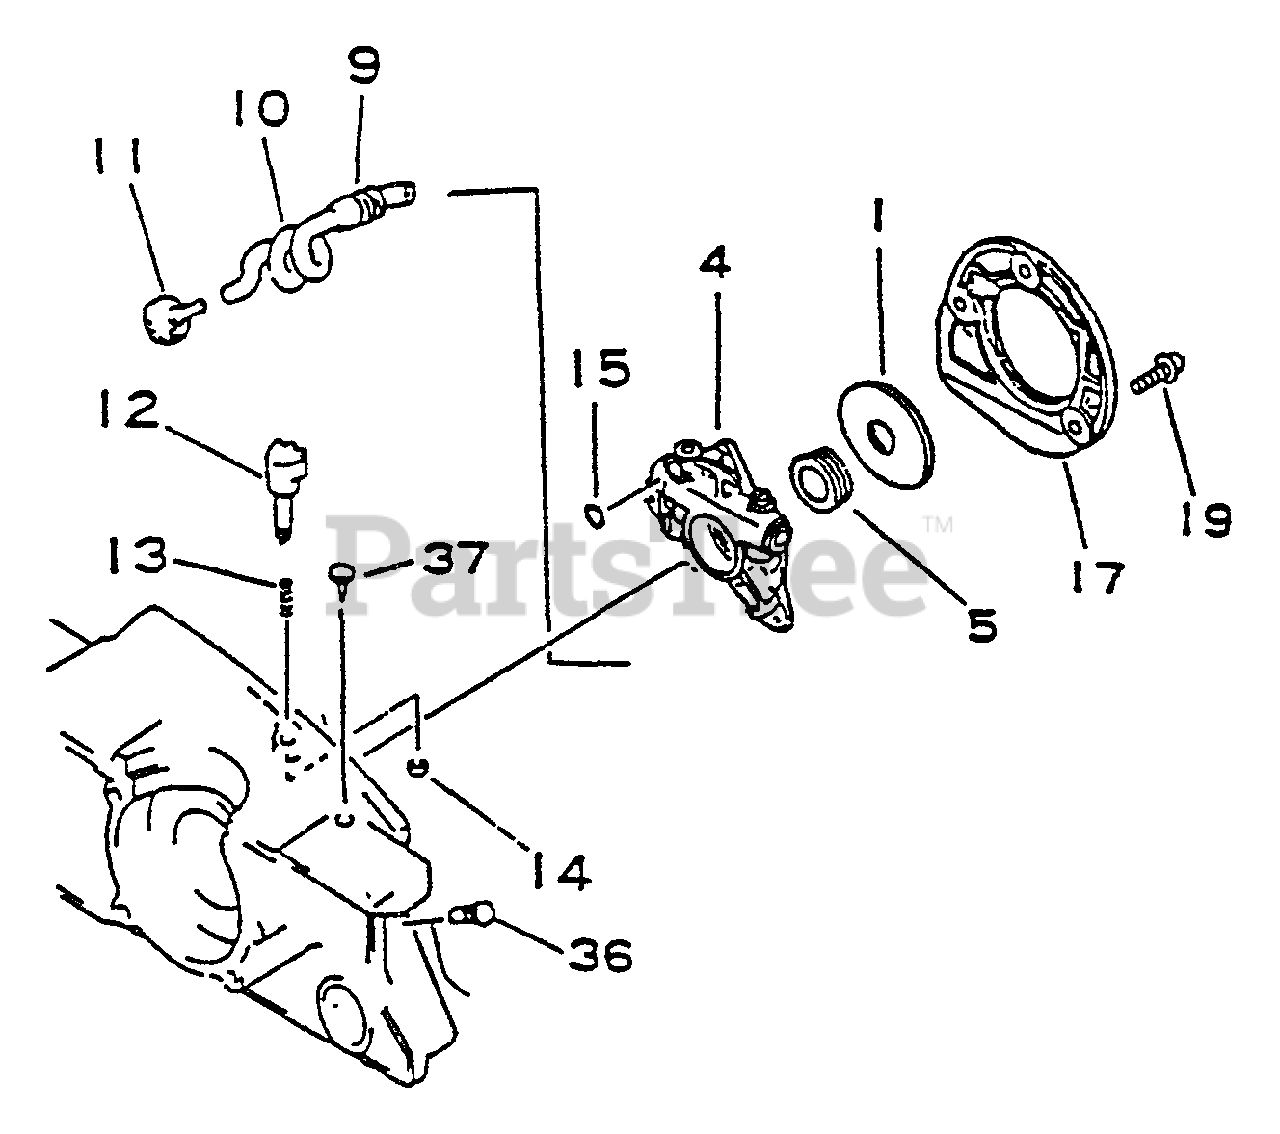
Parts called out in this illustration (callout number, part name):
1	GEAR, WORM
4	AUTO-OILER KIT
5	GEAR, WORM
10	PIPE, OIL
11	FILTER, OIL
14	E-RING 3
15	O-RING 3
17	COVER, OIL PUMP - GRAY
19	SCREW 4×14
36	PLUG
